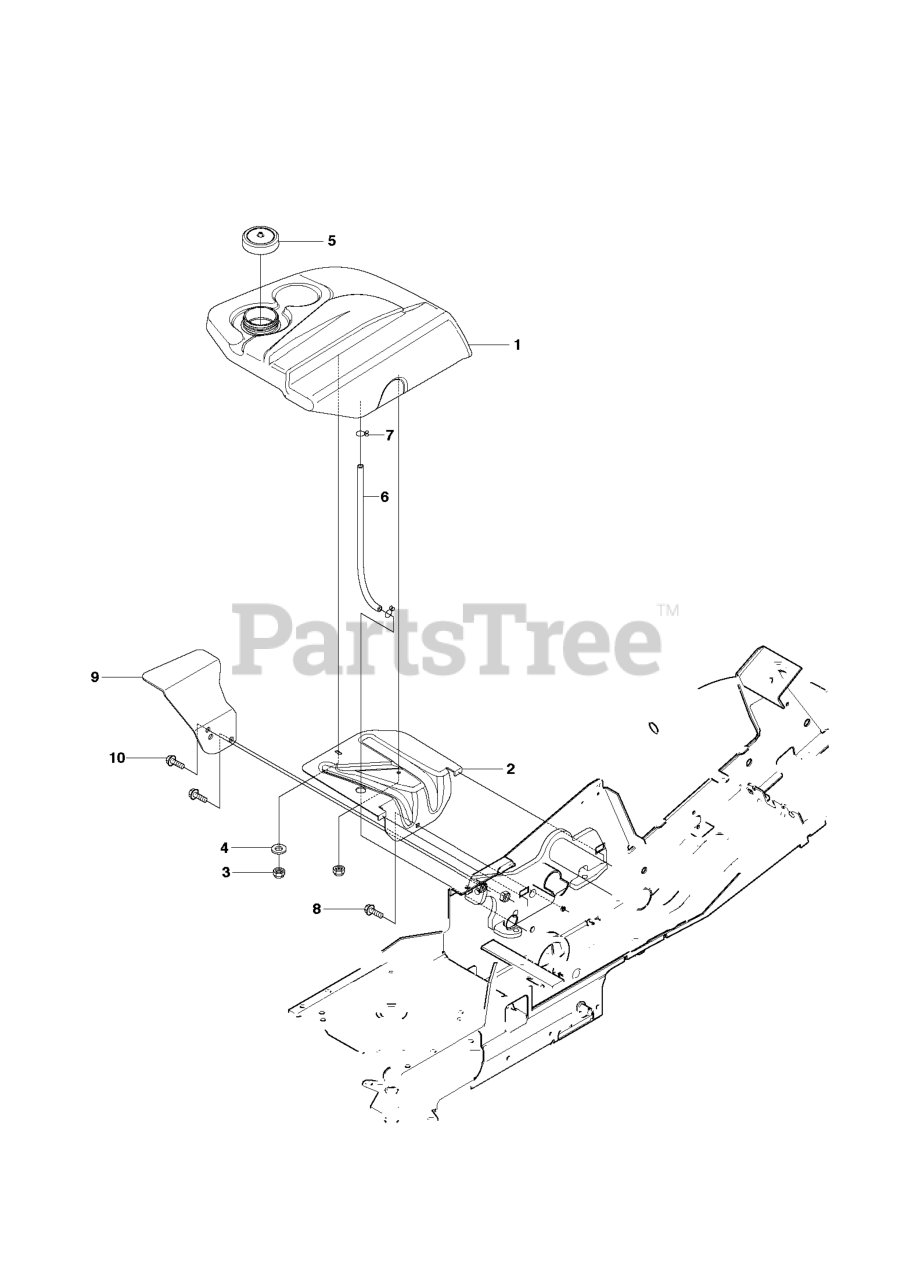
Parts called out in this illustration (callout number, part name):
3	LOCKNUT M6
4	WASHER
10	Screw M10x25
